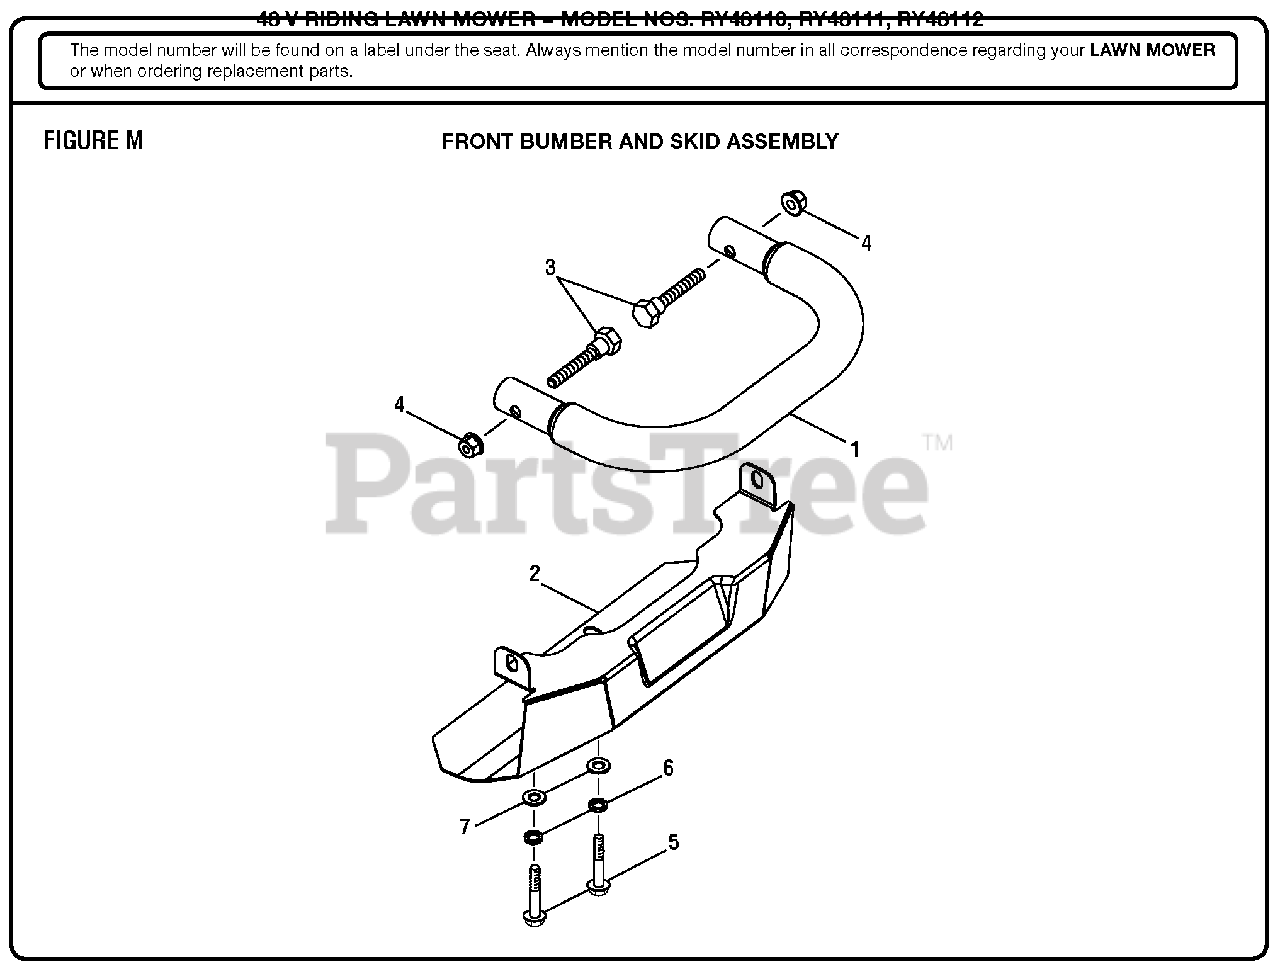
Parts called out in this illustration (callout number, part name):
1	Mower Bumper Tube
2	Front Bumper Cover
3	Shoulder Bolt (M8 x 50 mm)
4	Lock Nut (M8 x 1.25)
5	Shoulder Bolt (M8 x 45 mm, Hex Flange Hd.)
6	Lock Washer (8 mm)
7	Washer (OD16 x ID8.4 x 1.6t)
